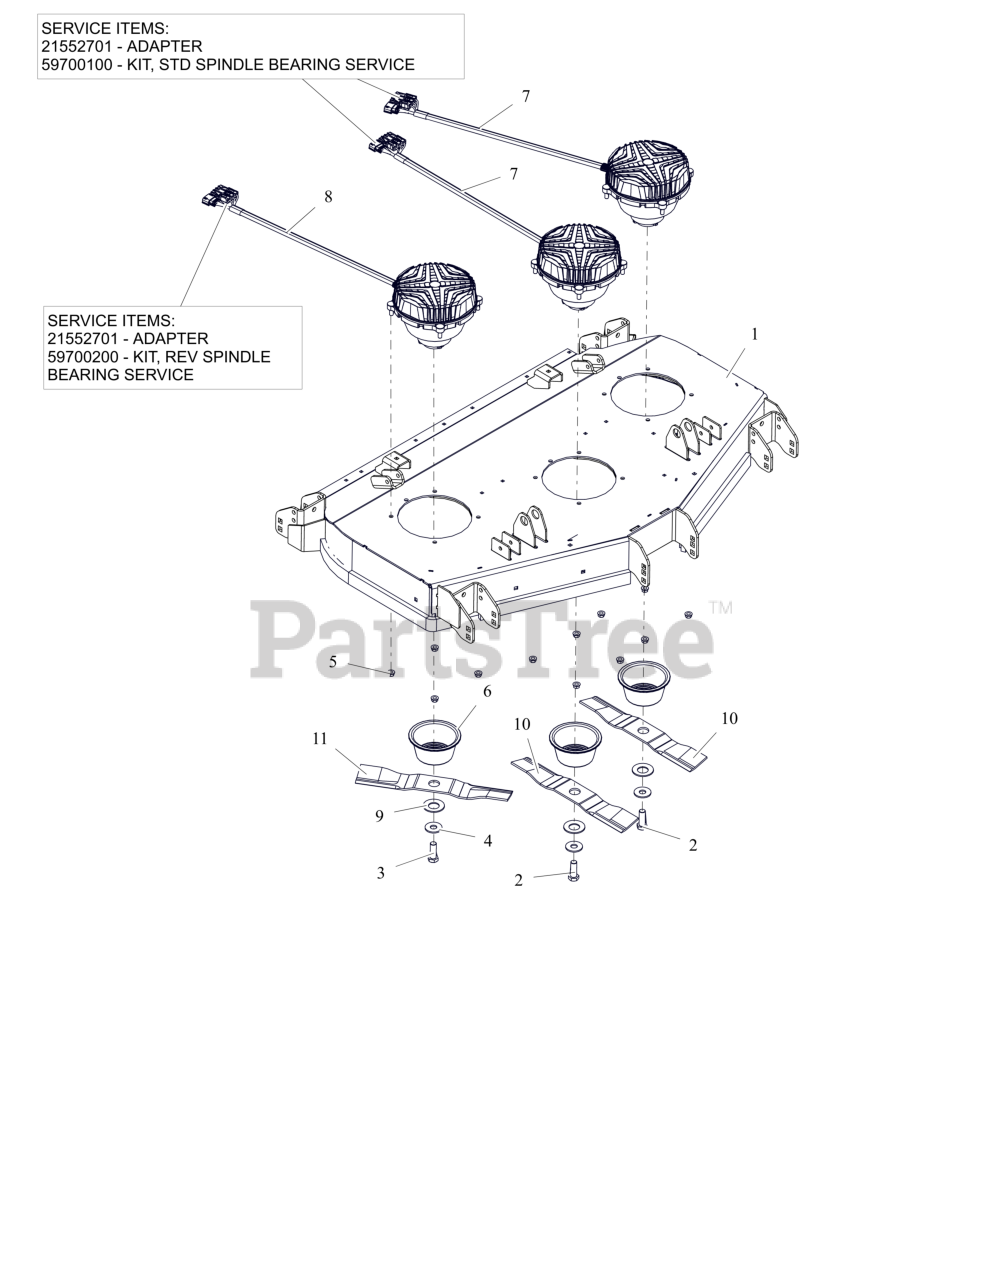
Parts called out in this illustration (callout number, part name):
1	KIT,DECK 48 RD W/DECALS-A
2	BLT, HEX .62-18X1.75 G8 ZCC
3	BLT, HEX 0.625-11X1.75 GR8 ZCC LH
4	WSHR, HRDN 0.687X1.75X0.134 HRD
5	NUT-LK-CTR-FLG .375-16 GF ZCC
6	GUARD, SPINDLE LOWER
7	MOTOR, DECK - 48"/52" CW
7	ADAPTER
7	KIT,STD SPINDLE BEARING SERVICE
8	MOTOR, DECK - 48"/52" CCW
8	ADAPTER
8	KIT,REV SPINDLE BEARING SERVICE
9	WSHR, BLVL - .56X28.5X3 PHOS.COAT
10	BLADE- MOWER-16.19" LOW
11	BLADE, MOWER -16.190" EFF CCW
